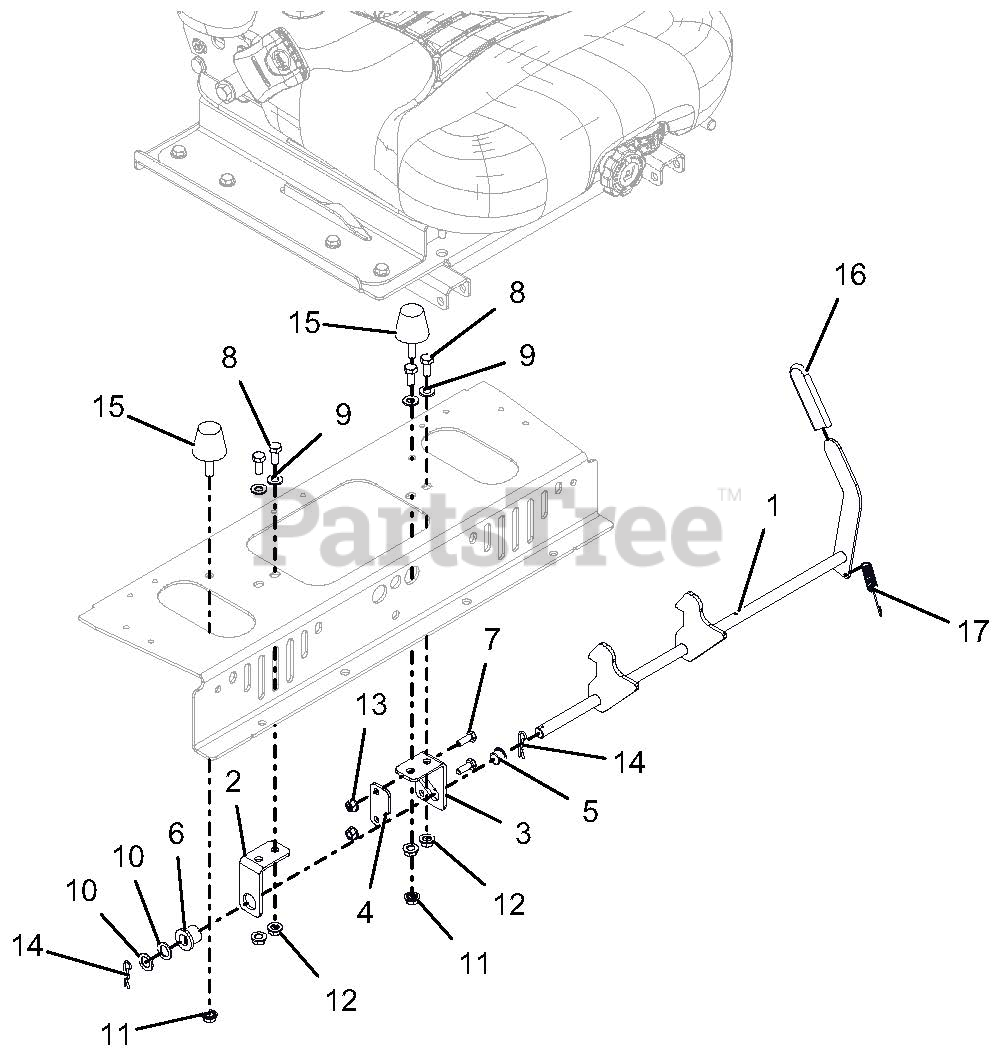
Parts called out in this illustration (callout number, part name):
1	WMT-SEAT LATCH
2	MOUNT, SEAT LATCH - RH
3	MOUNT-SEAT LATCH-LH
4	RETAINER-SEAT LATCH
5	BUSHING, POLYLINER - .50 SPLIT
6	BSHG-FLG .515X.750X.745X1.00NY
7	@BLT-HEX .25-20X.75 GR5 YWZC
8	@BLT-HEX .31-18X.75 GR5 YWZC
9	@WSHR-FL-STL.344X.688X.065YWZC
10	WSHR-FL-STL .52X.827X.062 YWZC
11	@NUT-SPNLK-FLG .312-18 YWZC
12	@NUT-LK-TOP-FLG .31-18 YWZC
13	@NUT-LK-TOP-FLG .25-20 YWZC
14	PIN-HAIR INT .08X.38X1.42 YWZC
15	BUMPER,STUD MOUNTED CONE SHAPE
16	GRIP-VINYL-YELLOW .125X1.0X3.0
17	SG-TENS .043X.44X3.31 WLD 5.8
